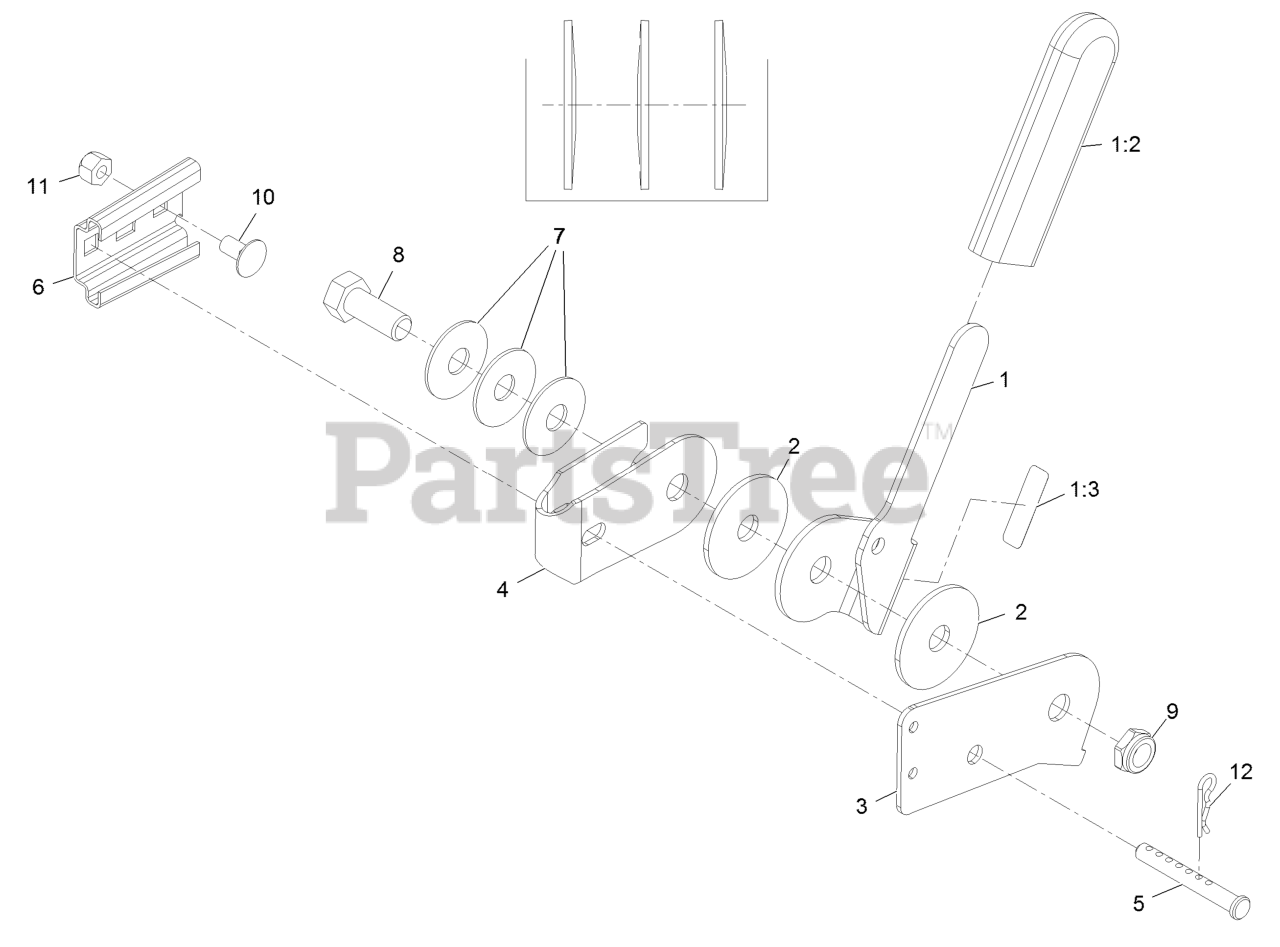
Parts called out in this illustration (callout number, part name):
1	CONTROL HANDLE ASM-OCD
1:2	GRIP-LEVER
1:3	Decal-Operation
2	DISC-FRICTION
3	BRACKET,CONTROL MOUNT
4	BRACKET,HANDLE MOUNT
5	PIN-CLEVIS
6	BRACKET-MOUNTING,SMV
7	WASHER-DISC, SPRING
8	SCREW-HH
9	NUT-HEX
10	SCREW-CARR
11	NUT-LOCK, NI
12	PIN-COTTER
